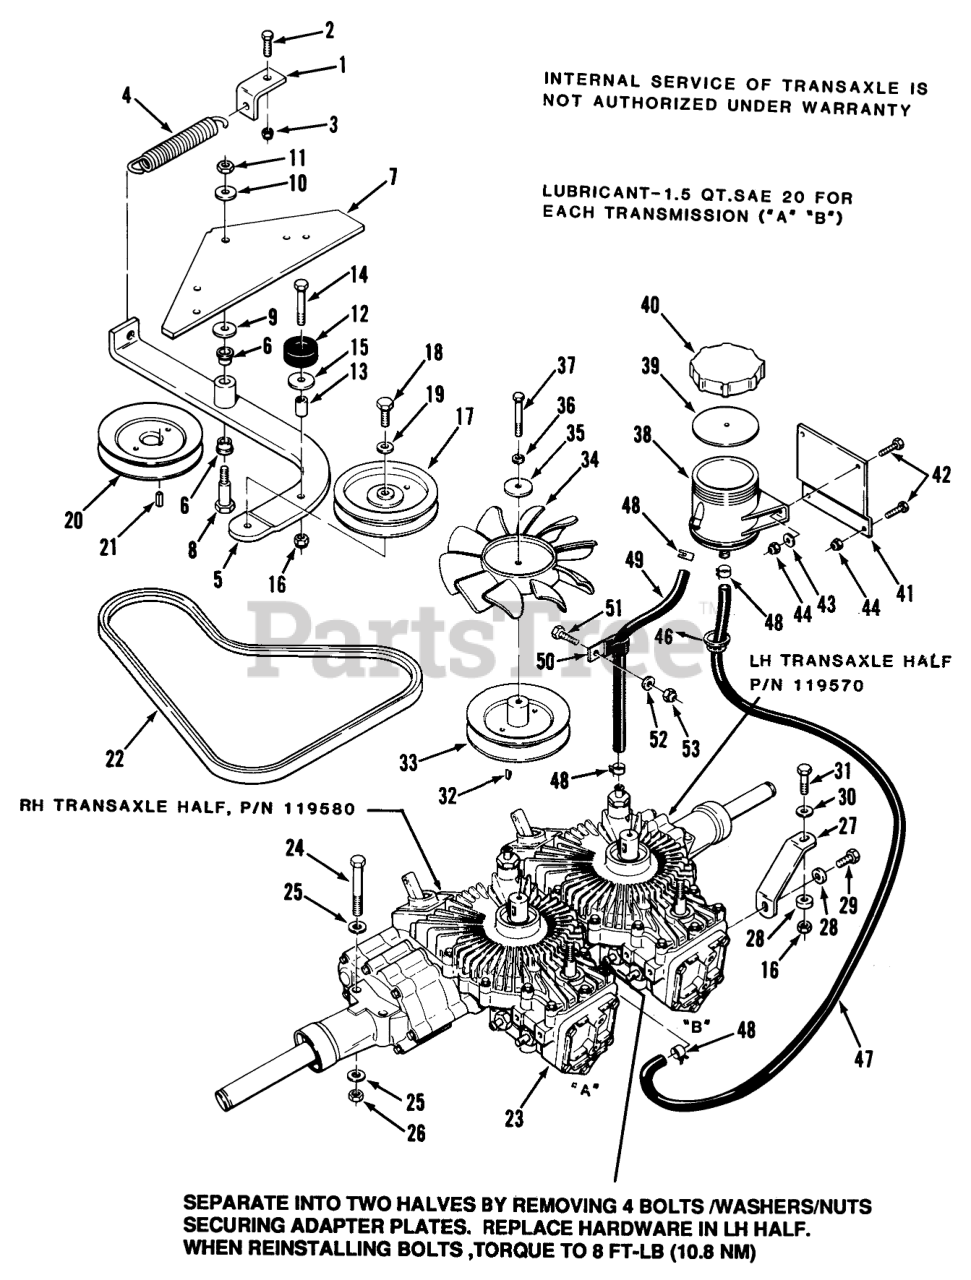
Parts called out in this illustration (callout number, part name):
1	BRACKET-SPRING
2	Bolt
3	Nut
4	SPRING-EXTENSION
5	Arm-Idler
6	BUSHING
7	Stiffener
8	BOLT-SHOULDER
9	WASHER
10	Washer
11	Nut
12	BUMPER
13	SPACER
14	Bolt 5/16-18 x 2
15	WASHER
16	Nut
17	PULLEY IDLER
18	BOLT
19	Washer
20	PULLEY
22	V-BELT
23	Transaxle Assembly
24	Bolt
25	Washer
26	NUT
27	BRKT-HYDRO SIDE
28	WASHER-SPECIAL
29	Bolt
30	WASHER 5/16 SAE
31	Bolt
32	KEY WOODRUFF
33	PULLEY
34	FAN-7"
35	WASHER
36	Washer
37	Bolt 1/4-20 x 2
38	ASS'Y-RESERVOIR
39	COVER GASKET
40	Cover
41	BRKT-RESERVOIR R
42	Bolt
44	Nut
46	BUSHING-NYLON 1.093
47	HOSE - 24" OF 114702
48	CLAMP
49	HOSE - 9.5" OF 114702
50	PIN HITCH UPPER LINK
51	Bolt
52	WASHER 5/16 SAE
53	Nut
